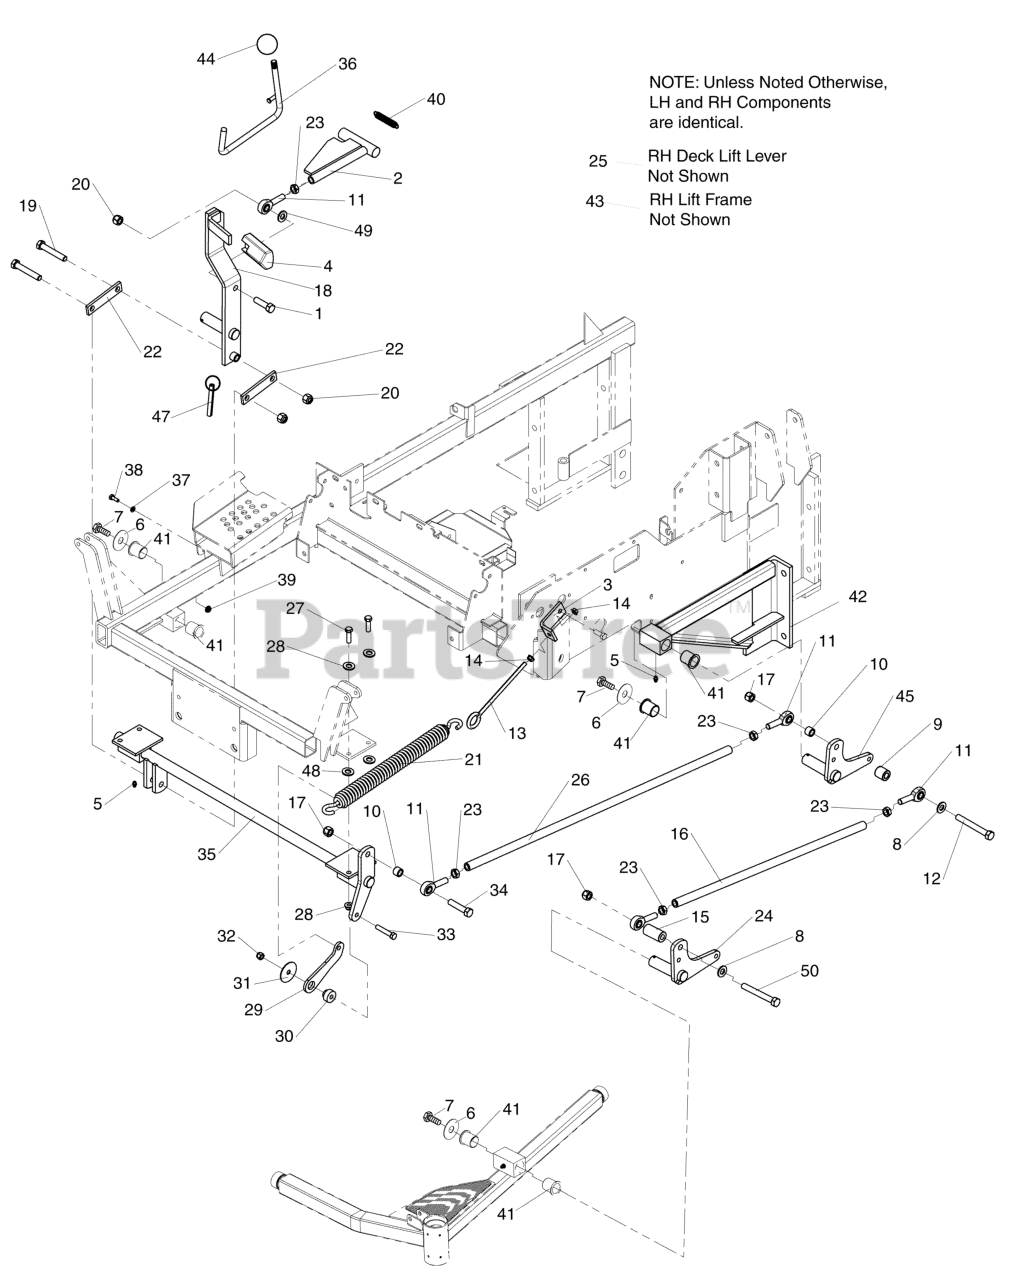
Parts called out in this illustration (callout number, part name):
1	BOLT, 1/2-20 X 1-3/4" GD8 CZ
2	WELD, DECK ADJUST LINK
3	ANCHOR, EYEBOLT
4	PEDAL, Rubber
5	GREASE FITTING, 1/4-28 STRAIGHT
6	WASHER, .390 X 1.50 X .109
7	BOLT, 3/8-16 X 3/4, PLT W/PATCH
8	WASHER, 1/2" GD9 YZ
9	SPACER, .52 X 1.00 X 1.00
10	SPACER, .51 X .75 X .56
11	BALL JOINT, 1/2-20, MALE
12	BOLT, 1/2-13 X 4" GD5 CZ
13	EYE BOLT, 3/8-16 X 8", 1" EYE
14	NUT, 3/8-16 HEX
15	SPACER, .52 X 1.00 X 1.15
16	ROD, DECK LIFT OUTER
17	NUT, 1/2-13 HEX NYLON LOCK
18	WELD, DECK LIFT PEDAL - RED
19	BOLT, 1/2-20 X 3" GD5 YZ
20	NUT, Hex, Nylon Lock, 1/2-20
21	SPRING, DECK LIFT ASSIST
22	LINK, DECK LIFT - RED
23	NUT, 1/2-20 HEX JAM
24	WELD, DECK LIFT LEVER, LH - BLK
26	ROD, DECK LIFT INNER
27	BOLT, 3/8-16 X 1-1/4" GD5 CZ
28	NUT, 3/8-16 HEX NYLOCK FLANGE
29	LINK, SPRING
30	BUSHING, DECK PIVOT
31	WASHER, .39 X 2.00 X X .14
32	WASHER, 3/8 SAE
33	BOLT, 3/8-16 X 2, GD5, CZ
34	BOLT, 1/2-13 X 2-1/4" GD5 CZ
35	WELD, LIFT SHAFT, IS5000Z - RED
36	WELD, ROD DECK LIFT
37	WASHER, 5/16" SAE
38	BOLT, 5/16-18 X 3/4 GD5
39	NUT, 5/16-18 HEX NYLOCK FLANGE
40	SPRING, EXTENSION
41	BUSHING, 1.00 X 1.13 X 1.38, PLASTIC
42	ASSM, REAR DECK LIFT LH
44	KNOB, PLASTIC, 1/2-13
45	WELD, DECK LIFT LEVER, LH - RED
47	PIN, COTTERLESS
48	WASHER, 3/8" GD.9 FLAT
49	WASHER, 1/2 SAE
50	BOLT, 1/2-13 X 3" GD5 CZ
